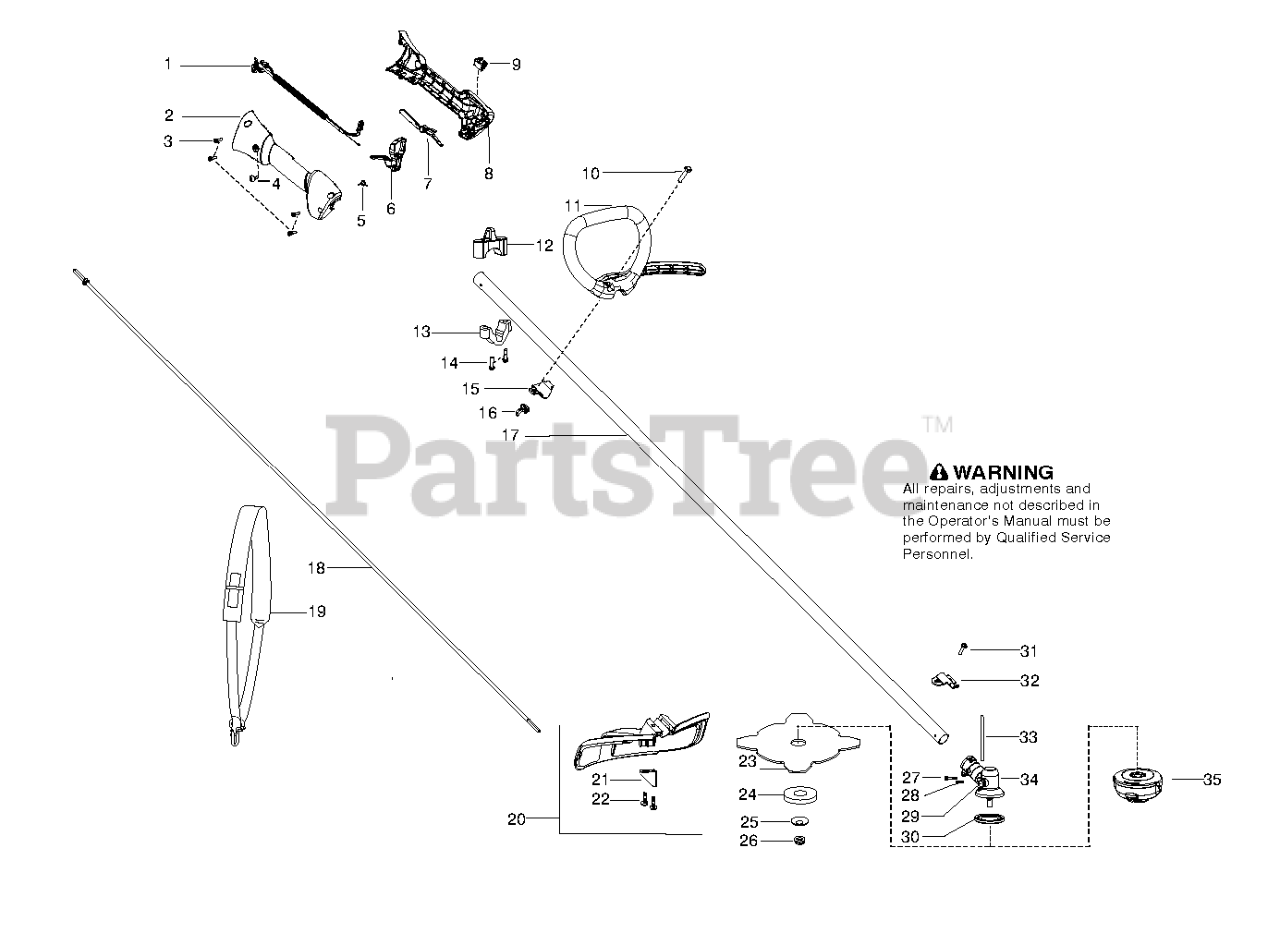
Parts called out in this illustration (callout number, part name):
1	ASSY CABLE / WIRE HARNESS
2	HSG THROTTLE RIGHT HVA
3	SCREW M4 X 1.75 PT 16MM
4	SCREW-10-14 X 1/2 PLASTITE
5	SPRING TRIGGER
6	TRIGGER THROTTLE HVA ORANGE
7	THROTTLE LOCKOUT HVA ORANGE
8	HSG THROTTLE LEFT HVA
9	SWITCH
10	BOLT, TYPE 2
11	ASSY HANDLE JBAR
12	CLAMP HARNESS UPPER
13	CLAMP HARNESS LOWER
15	CLAMP ASSIST HANDLE
16	WINGNUT, TYPE 2
17	Kit-Driveshaft
18	FLEXSHAFT 57"
19	Harness-w/o warning
20	KIT COBI SHIELD
21	Limiter - Line
23	Blade - Grass
24	SUPPORTING CUP
25	SUPPORT FLANGE
26	GEARHEAD NUT - BRUSHCUTTER
27	SCREW - CARB. ADAPTOR
29	PLUG GREASE 9MM
30	DRIVE DISC
31	SCREW 1/4-20 X 7/8 (TAP
32	BRACKET SHIELD STRAIGHT SHAFT
33	LOCKING PIN
34	ASSY GEARBOX
35	T25 TRIM HEAD 10MM LH
